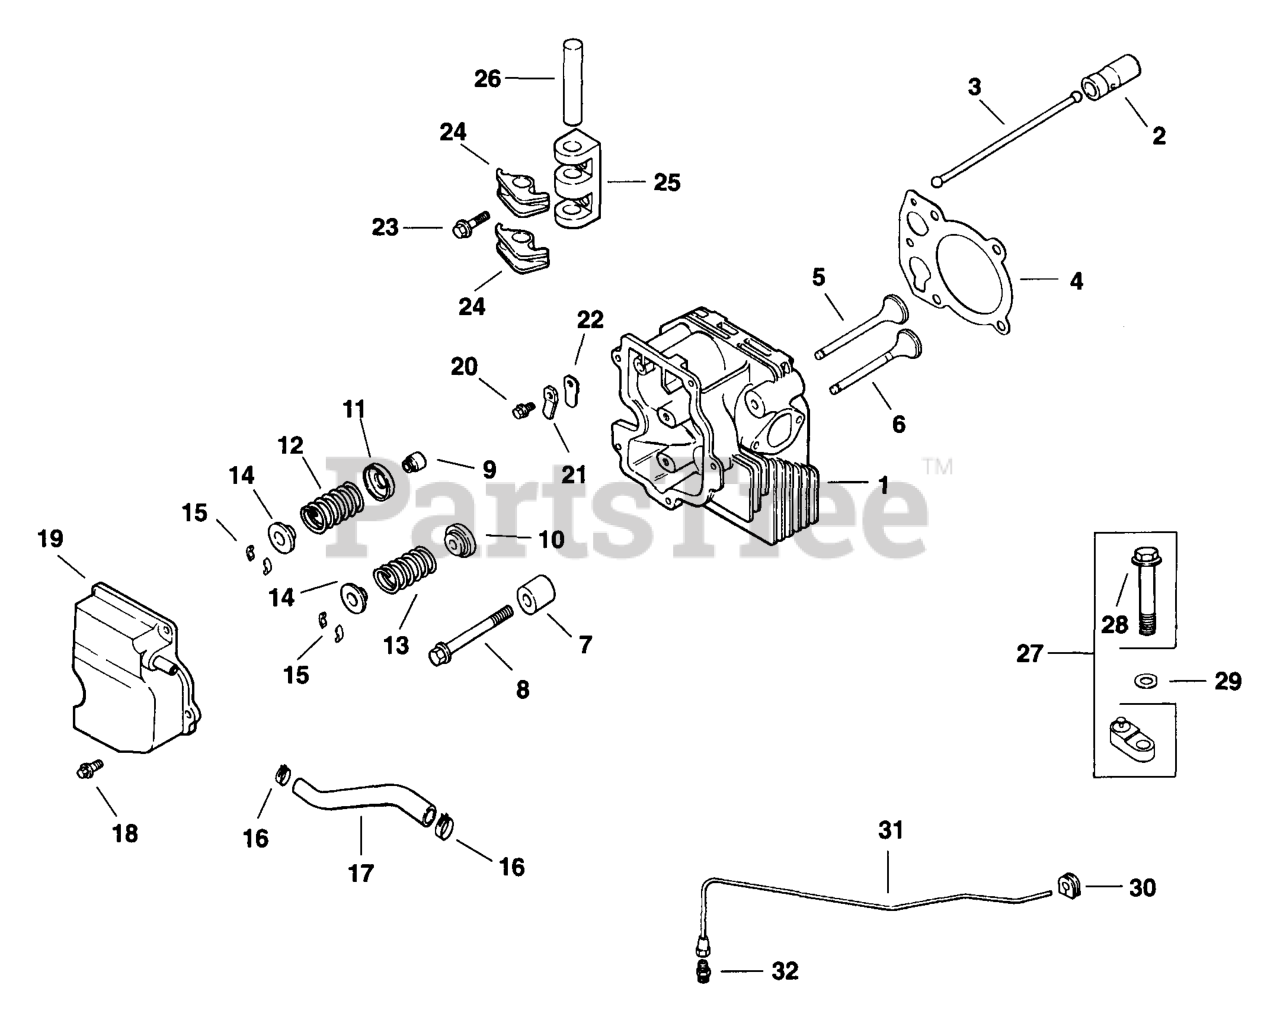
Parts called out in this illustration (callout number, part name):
1	KIT - USE 12 755 51
2	LIFTER - USE 12 351 02
4	GASKET, CYLINDER HEAD
5	VALVE, INTAKE
5	VALVE, INTAKE (.25 MM)
6	VALVE, EXHAUST
6	VALVE, EXHAUST (.25 MM)
7	KIT - USE 12 755 22
8	SCREW - USE 12 086 15
9	SEAL - USE 24 032 05
10	ROTATOR - DISCONTINUED
11	RETAINER - USE 235011
11	RETAINER, SPRING
13	SPRING-(#DSC)
14	RETAINER, VALVE SPRING - USE 25 173 28-S
15	KIT, RETAINER
16	CLAMP, HOSE 1/2" USE 25 237 14-S
18	SCREW - USE M-645020
20	SCREW - USE M-545010
21	RETAINER - UE 66 018 04-S
22	REED - USE 12 402 02
23	Screw, hex. flange M6x1.0x25
24	ARM - DISCONTINUED
26	SHAFT - (#DSC)
